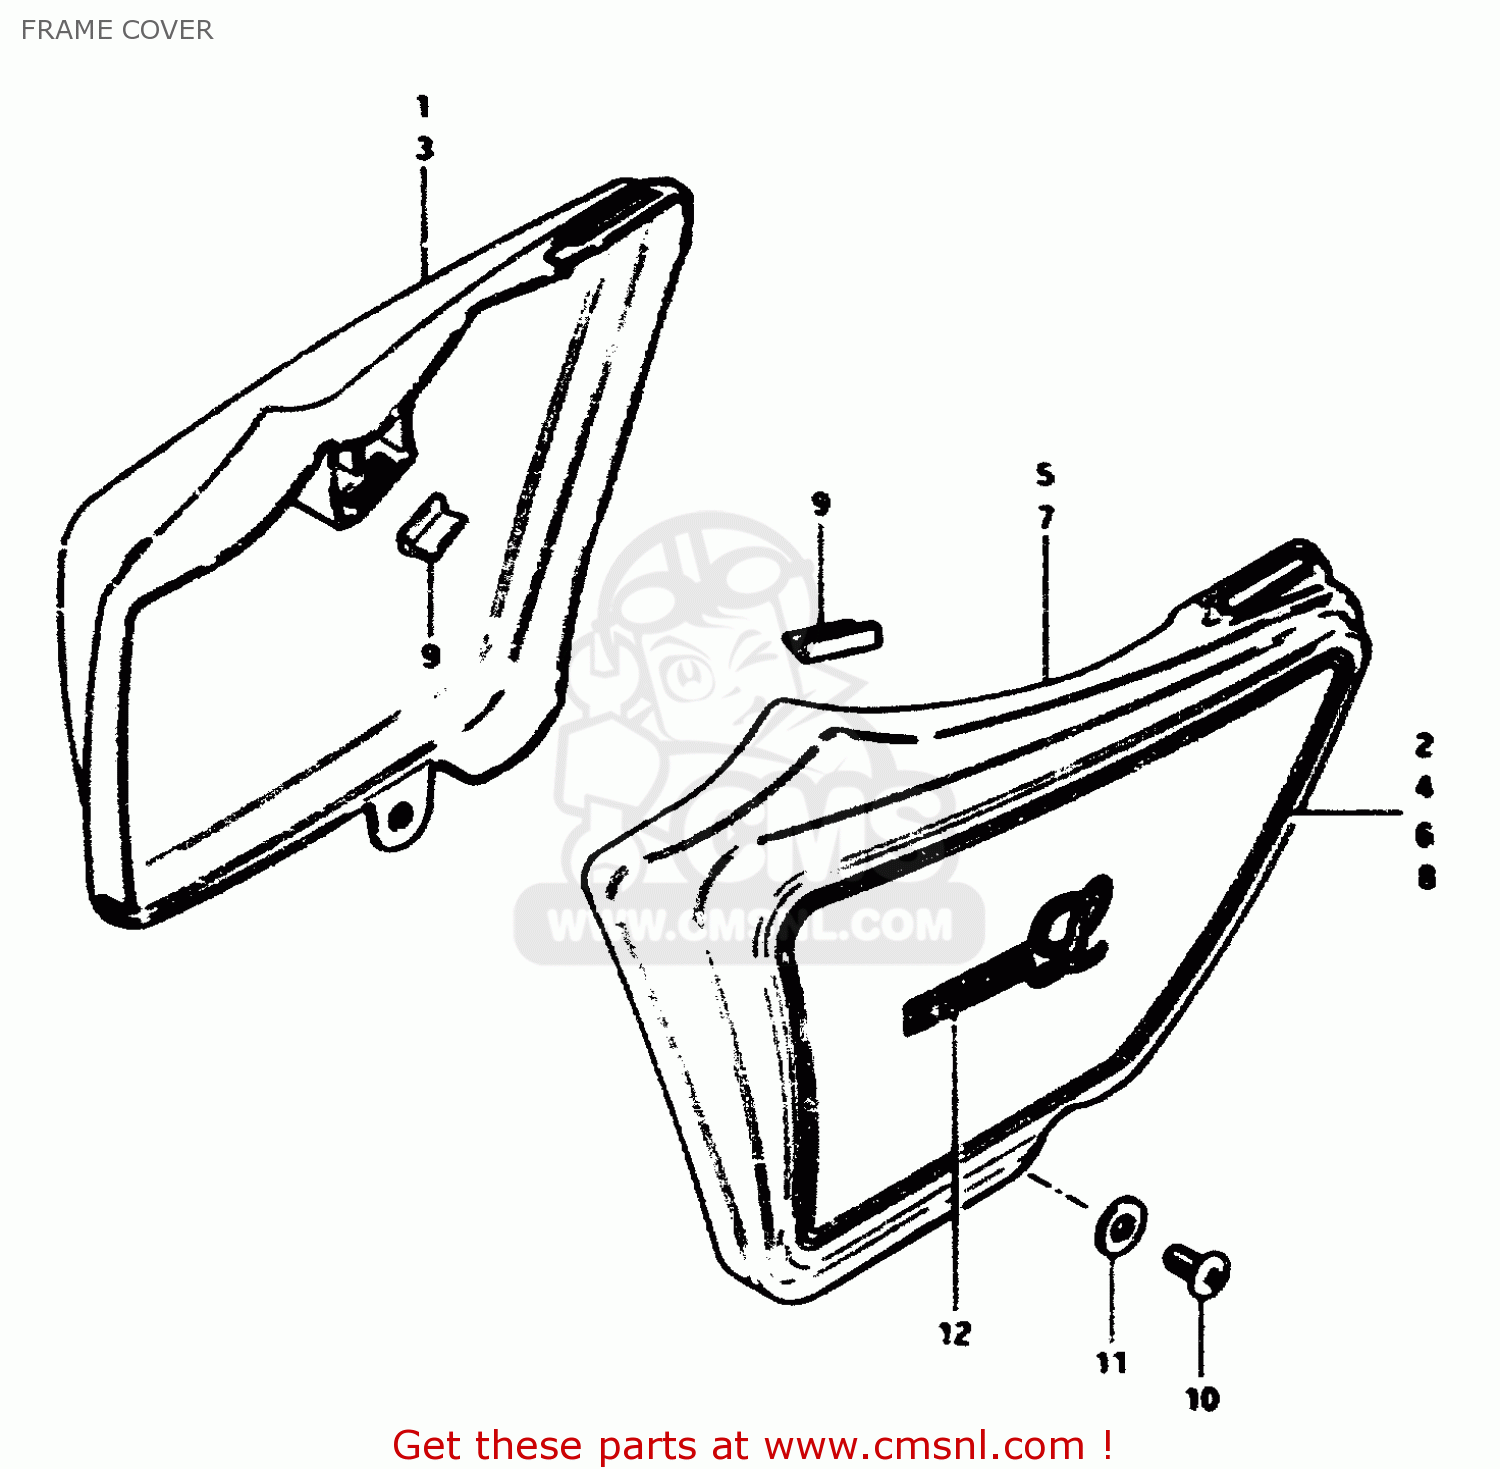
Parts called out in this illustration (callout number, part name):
1	COVER, FRAME RH (RED)
2	TAPE SET, RH
3	COVER, FRAME RH (YELLOW)
4	TAPE SET, RH
5	COVER, FRAME LH (RED)
6	TAPE SET, LH
7	COVER, FRAME LH (YELLOW)
8	TAPE SET, LH
9	CUSHION,FRAME COVER
10	SCREW
11	WASHER
12	EMBLEM
